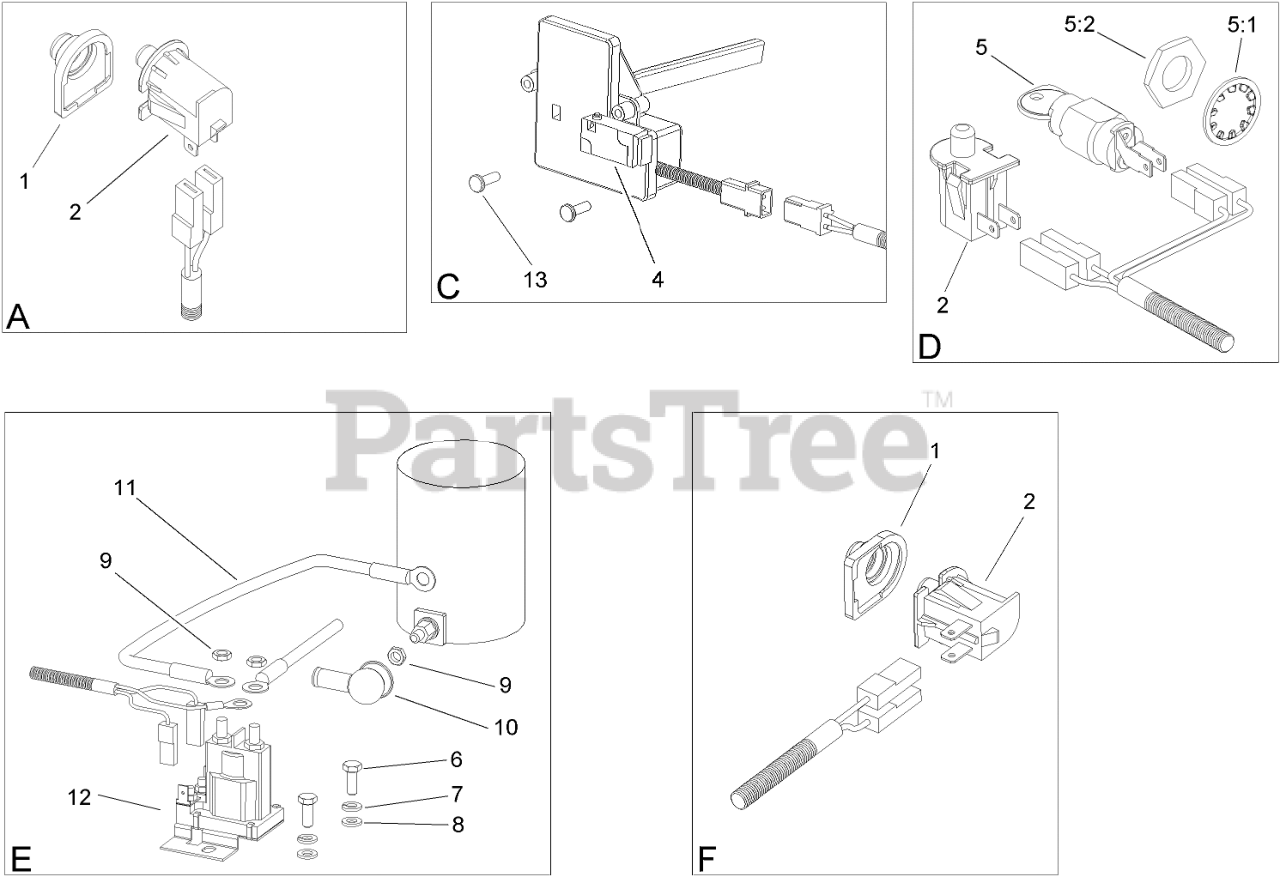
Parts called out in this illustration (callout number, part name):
1	COVER-PROTECTIVE
2	SWITCH-DELTA
4	SWITCH-OMRON
5	STARTER SWITCH ASM
5:1	WASHER-TOOTH, INTERNAL
5:2	NUT-HH
6	SCREW-HH
7	WASHER-SPRING
8	WASHER-FLAT
9	NUT-HHF
10	BOOT-RUBBER
11	LEAD-STARTER, ELECTRIC
12	SOLENOID
13	Screw
